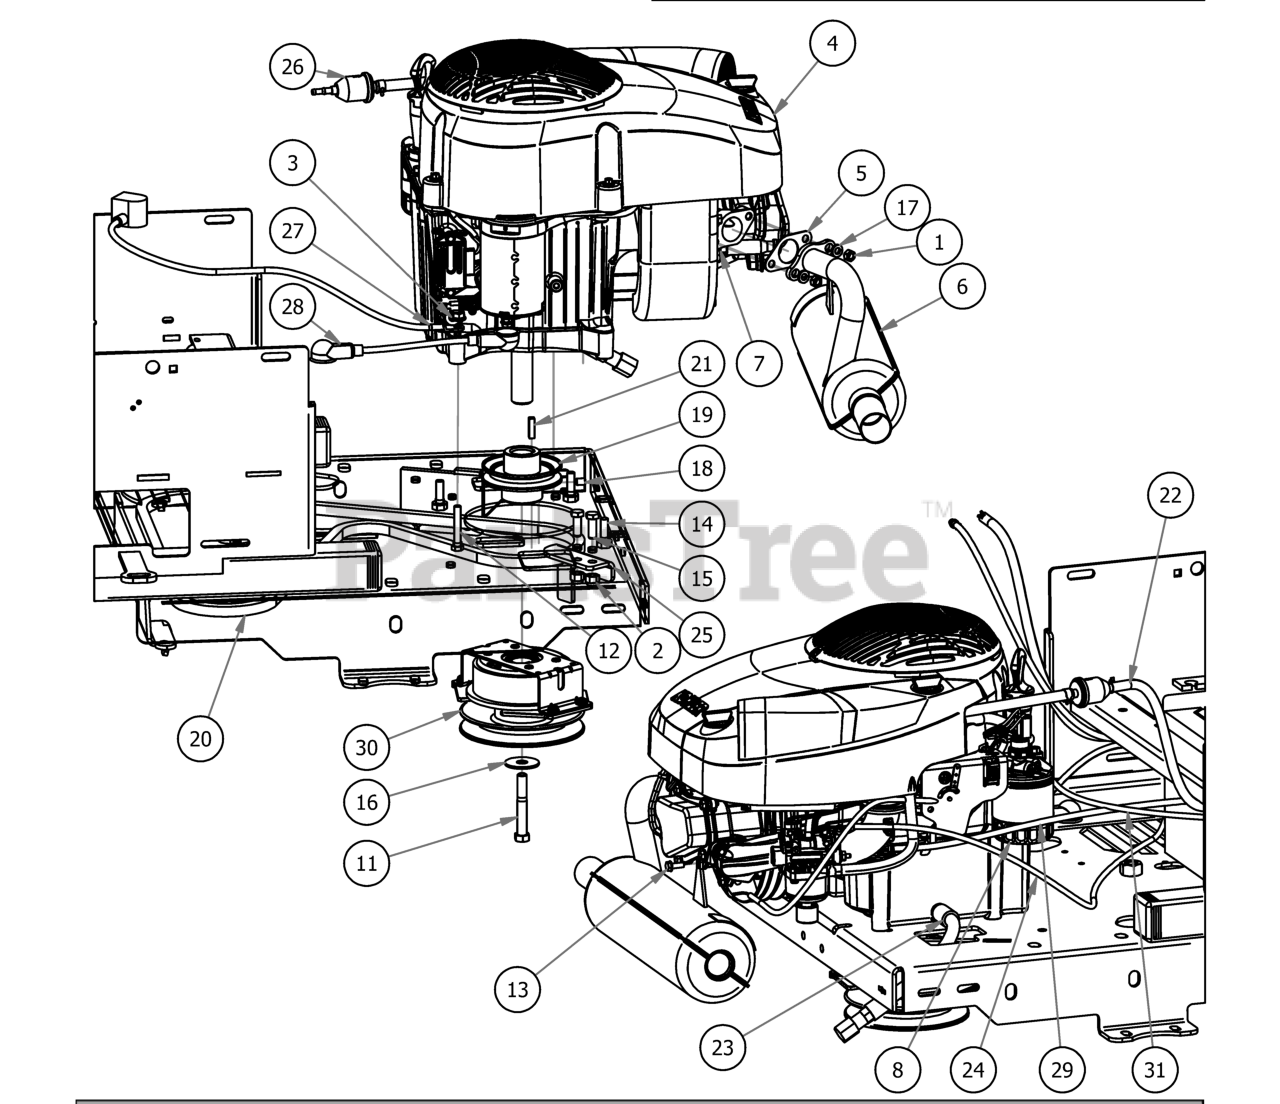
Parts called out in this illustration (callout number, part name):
1	M8-1.25 Zinc Nut
2	3/8 Nylock Nut
3	5/16" Flange Nut
4	Kohler KS-590 541cc 19Hp
5	Exhaust Gasket
6	Kohler KS-590 Muffler
7	Kohler KS-590 Spark Plug
8	Kohler KS-590 Oil Filter
9	Kohler KS-590 Air Pre-Cleaner
10	Kohler KS-590 Air Filter
11	7/16"-20 x 3" Hex Bolt Gr. 8
12	5/16-18 X 2 Hex C/S (GR.5) ZC
13	M6-1.0x16mm Self-Tapping Bolt
14	3/8 x 1 1/8 bolt
15	3/8" x 1" Hex Bolt
16	1/2" Belleville Washer
17	5/16" Lock Washer
18	3/8" Set Screw
19	3-3/4" Motor Pulley
21	1/4" x 1" Key
22	37" Fuel Line Assembly
23	Oil drain Hose
25	2017 MZ Clutch Stop
26	Universal In-line Fuel Filter
27	Ground Cable
28	12" Red Battery Cable
29	MZ Kohler EPA Canister Assembly
31	2017 MZ Control Panel Assembly
